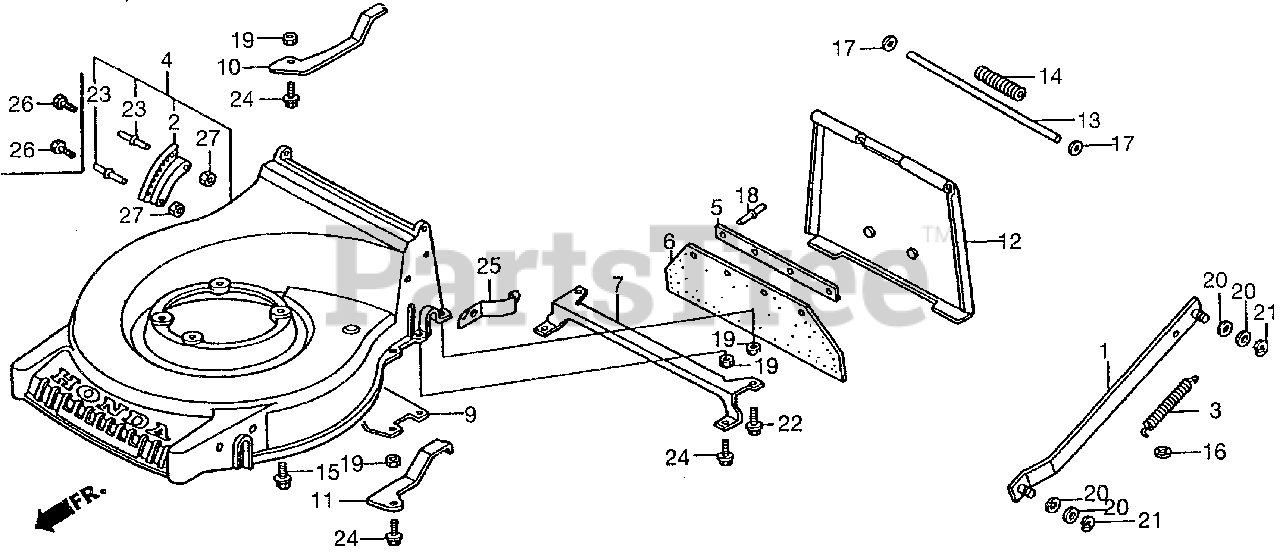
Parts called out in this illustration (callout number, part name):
1	ARM, ADJUSTER
2	PANEL, HEIGHT ADJUSTING
3	SPRING, BALANCER
4	HOUSING, CUTTER *NH355* (GRANITE GRAY)
5	PLATE, SAFETY SHIELD
6	SHIELD, SAFETY
7	HOLDER, RR. SHAFT
9	PLATE, SCROLL
10	PLATE, R. GUIDE
11	PLATE, L. GUIDE
12	GUARD, DISCHARGE
13	SHAFT, DISCHARGE GUARD
14	SPRING, GUARD RETURN
15	BOLT, ENGINE SETTING
16	NUT, PUSH (9.5MM)
17	WASHER, SPECIAL (6MM) (PUSH NUT)
18	RIVET, BLIND (4.8MM)
19	NUT, HEX. (6MM)
20	WASHER, PLAIN (10MM)
21	E-RING (7MM)
22	BOLT, FLANGE (6X12) Use up to Engine SN 1543277.
23	RIVET, BLIND (4.8MM)
24	BOLT, FLANGE (6X14)
25	PLATE, PLUG DISCHARGE
26	BOLT, RECESSED (5X12)
27	NUT, HEX. (5MM)
